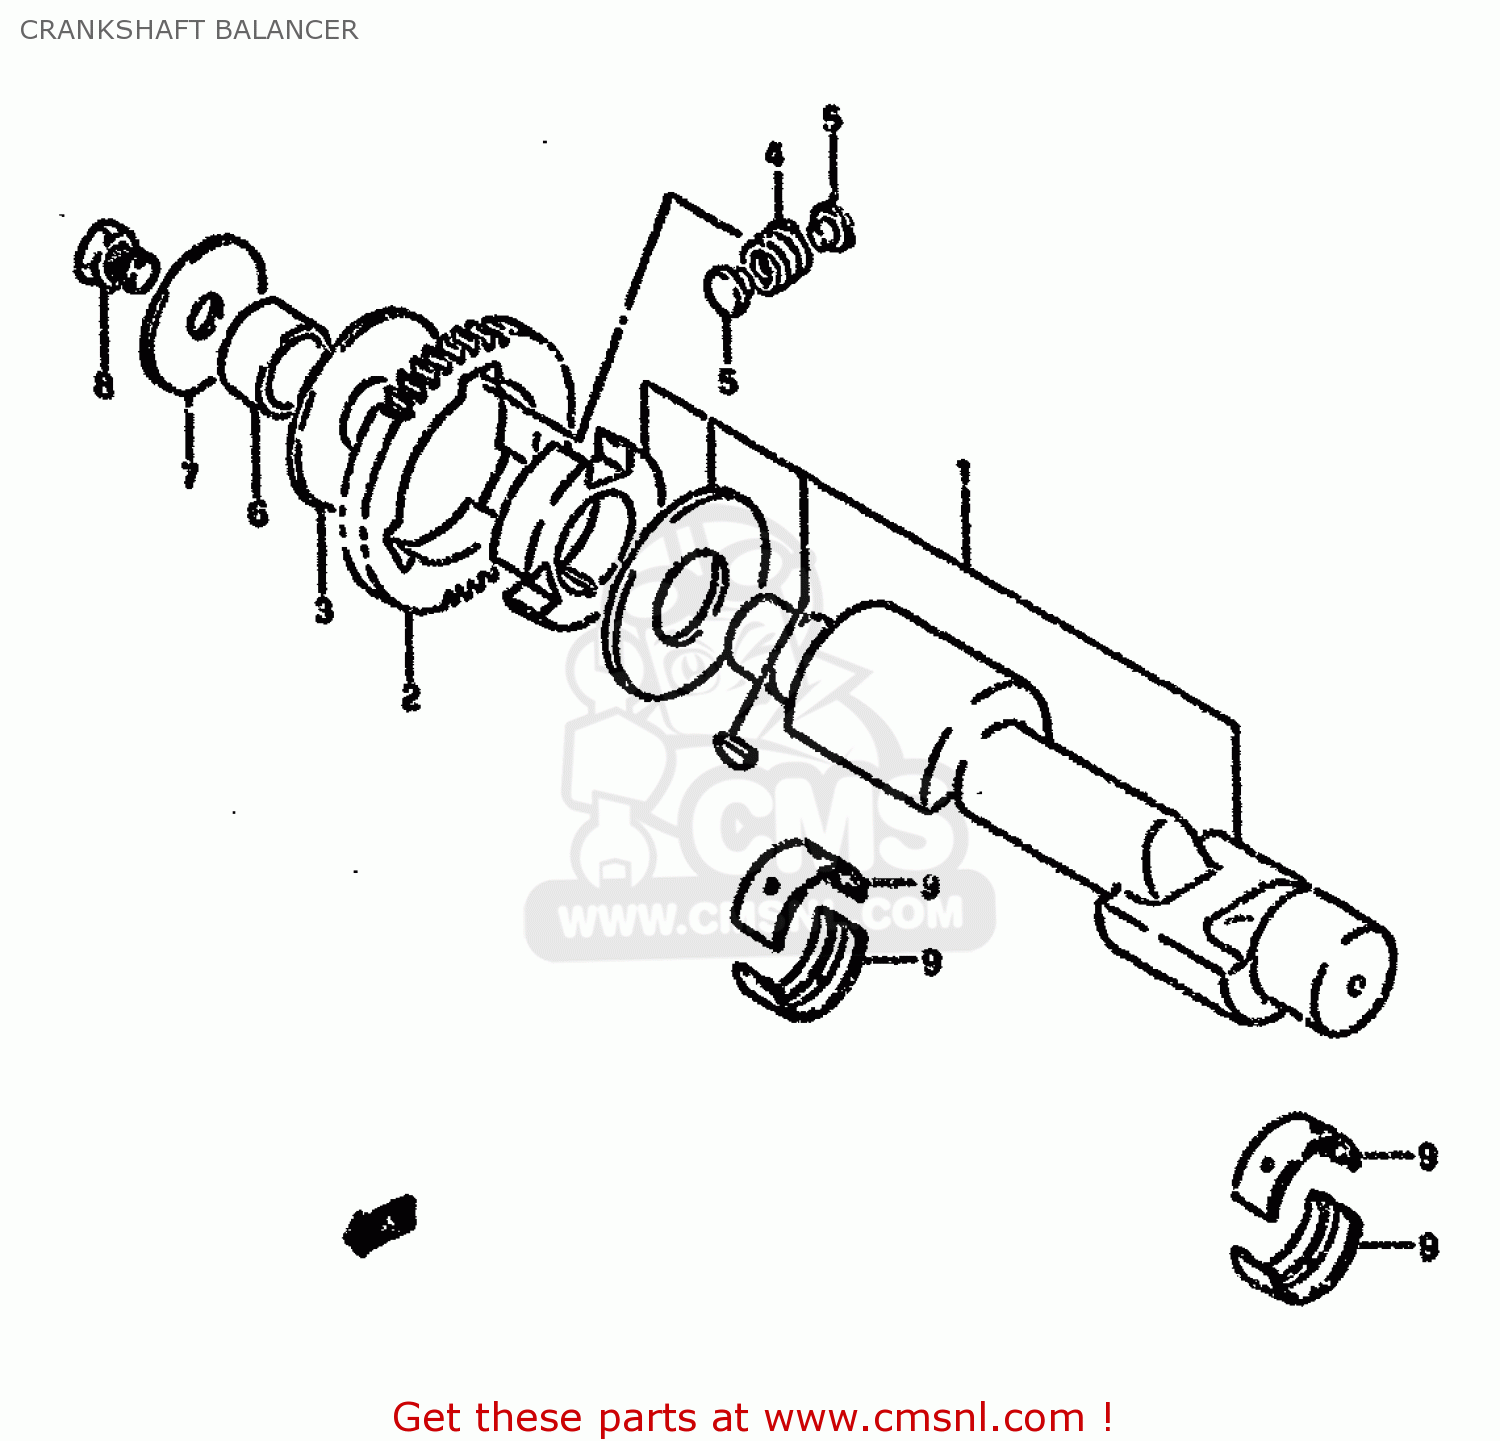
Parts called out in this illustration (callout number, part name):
1	BALANCER,CRANK
2	GEAR,CRANK BALANCER DRIVE
3	WASHER(24X70X3)
4	SPRING
5	PIN
6	SPACER
7	WASHER(12X50X3)
8	BOLT
9	BEARING,CRANKSHAFT(GREEN)
